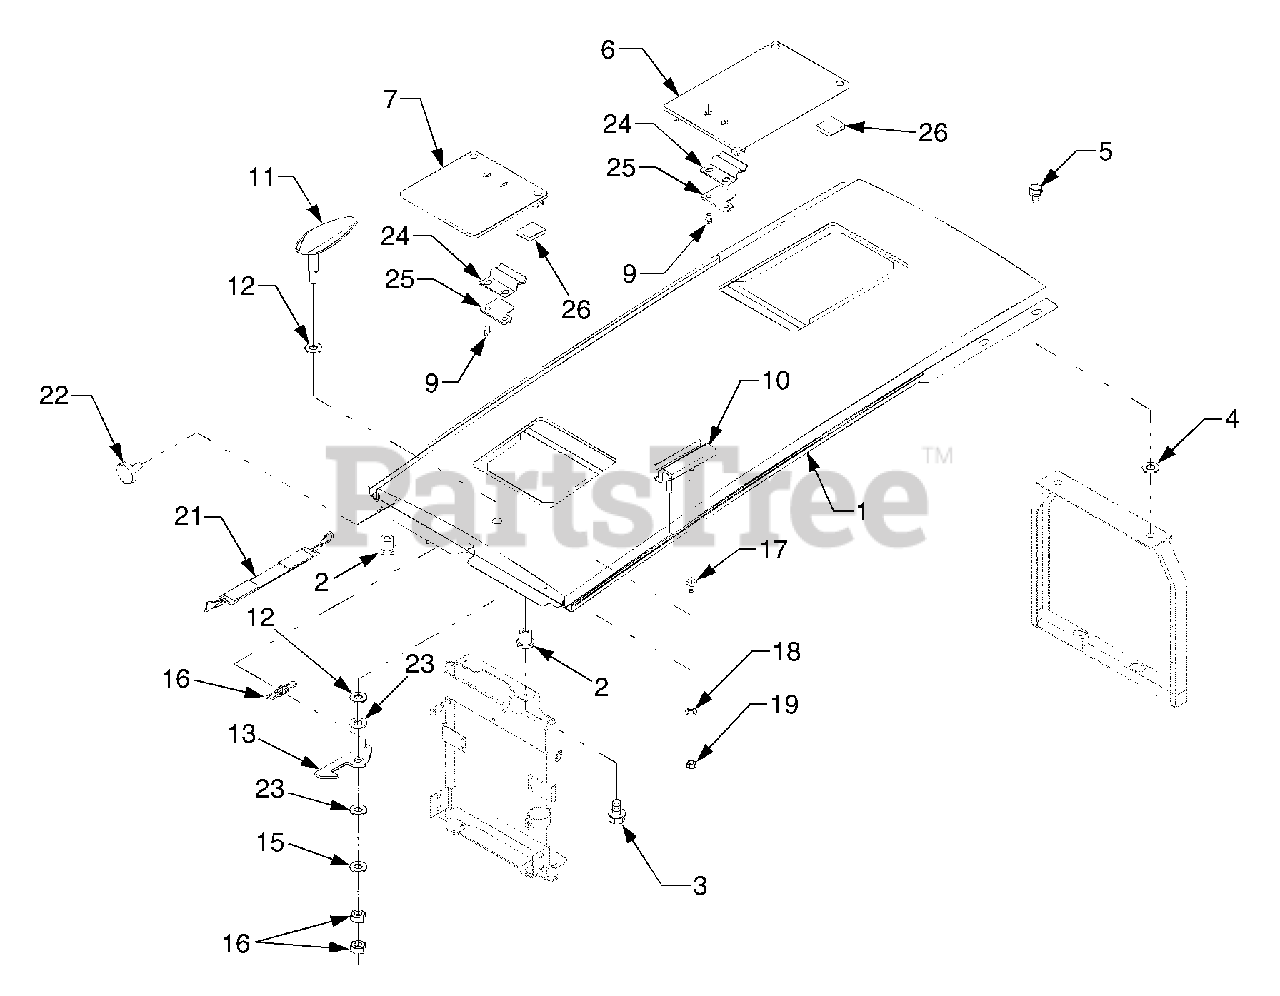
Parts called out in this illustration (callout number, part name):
1	Bonnet (Upper)
2	Rubber, Cushion
6	Cover 2 Ass'y
10	Cushion, Bonnet
11	Handle, Bonnet Lock
13	Plate, Front Grill
15	Washer, Plain
19	Washer, Spring
21	Hook Ass'y
25	Plate (B)
26	Cushion, Bonnet
